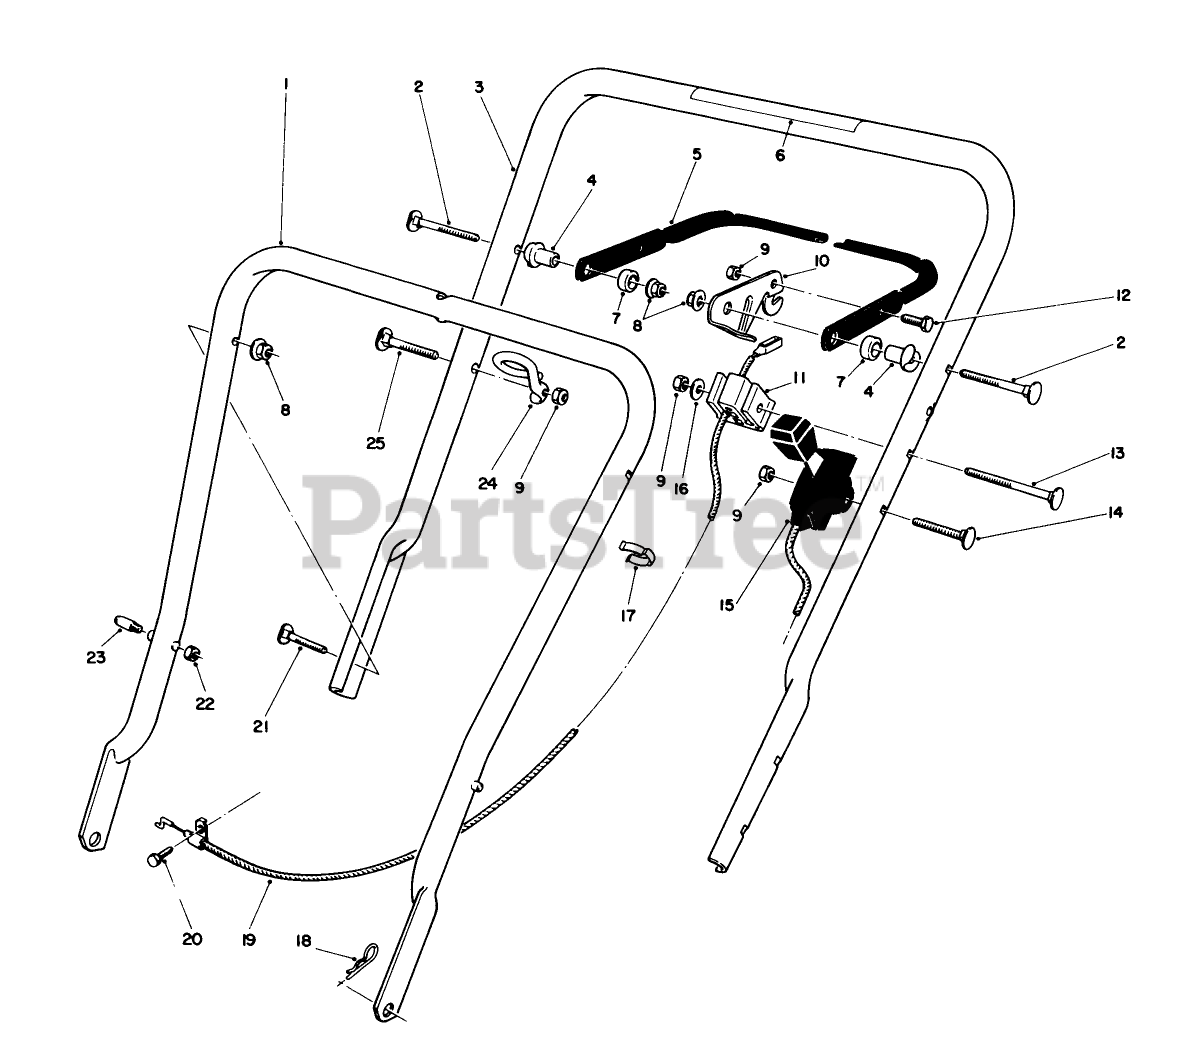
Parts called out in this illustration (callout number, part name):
1	LOWER HANDLE ASM
4	SPACER-SUPPORT
7	SPACER-NYLON
8	NUT-LOCK, NI
9	NUT-LOCK, NI
10	CONTROL LEVER
11	SUPPORT-CABLE
12	SCREW-HH
13	HANDLE SCREW
14	SCREW-HANDLE
16	WASHER-FLAT
17	BOWDEN CLIP
18	PIN-COTTER, HAIR
22	NUT-LOCK, NI
23	HANDLE PIN
25	HANDLE SCREW
